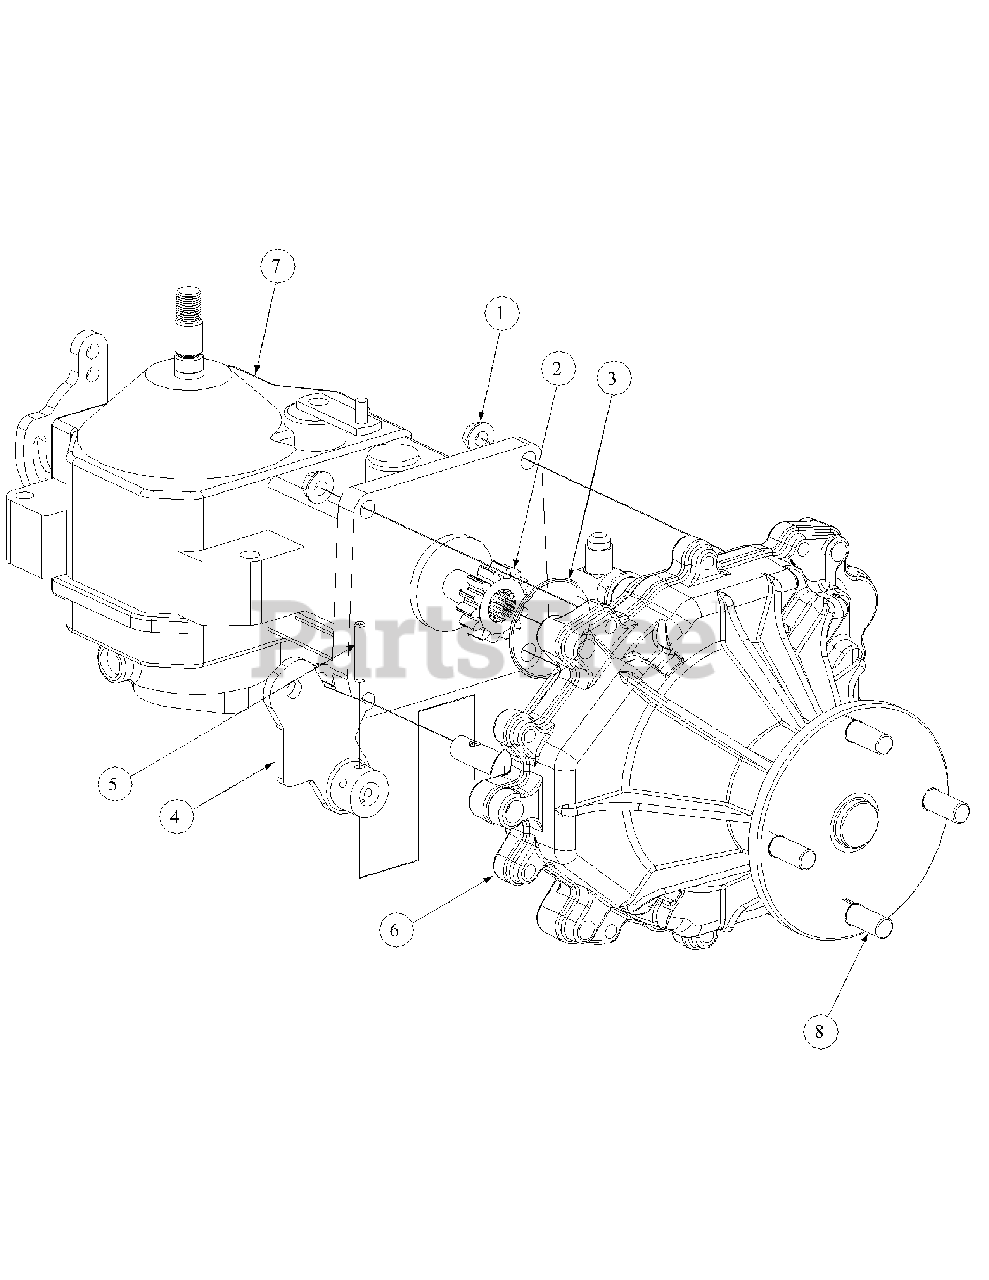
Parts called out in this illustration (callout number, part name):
1	Hex Flange, Lock Nut, 5/16-18
2	Gear, Spur, 14T
3	O-Ring, 2.00 x .070
4	Lever, Bracket, Park
5	Pin, Spirol, 3/16 x 1.25 HD
6	Transmission Assembly
8	Rib Neck Stud, 1/2-20
